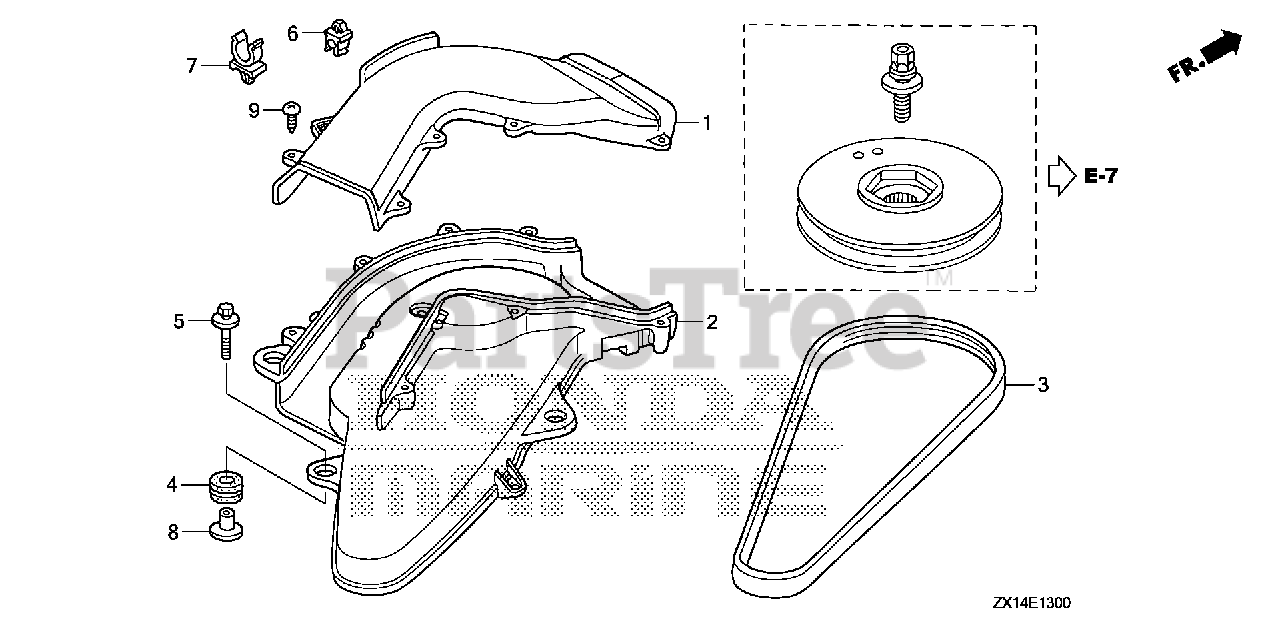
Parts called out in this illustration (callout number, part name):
1	DUCT A, MUFFLER
2	DUCT B, MUFFLER
3	BELT, ALTERNATOR (4PK810)
4	GROMMET, CASE (LOWER)
5	BOLT-WASHER (6X25)
6	CLIP, TUBE (3.5)
7	CLAMP (18.5MM)
8	COLLAR, MODULE IGNITION CONTROL CASE (CDI)
9	SCREW, TAPPING (5X20)
